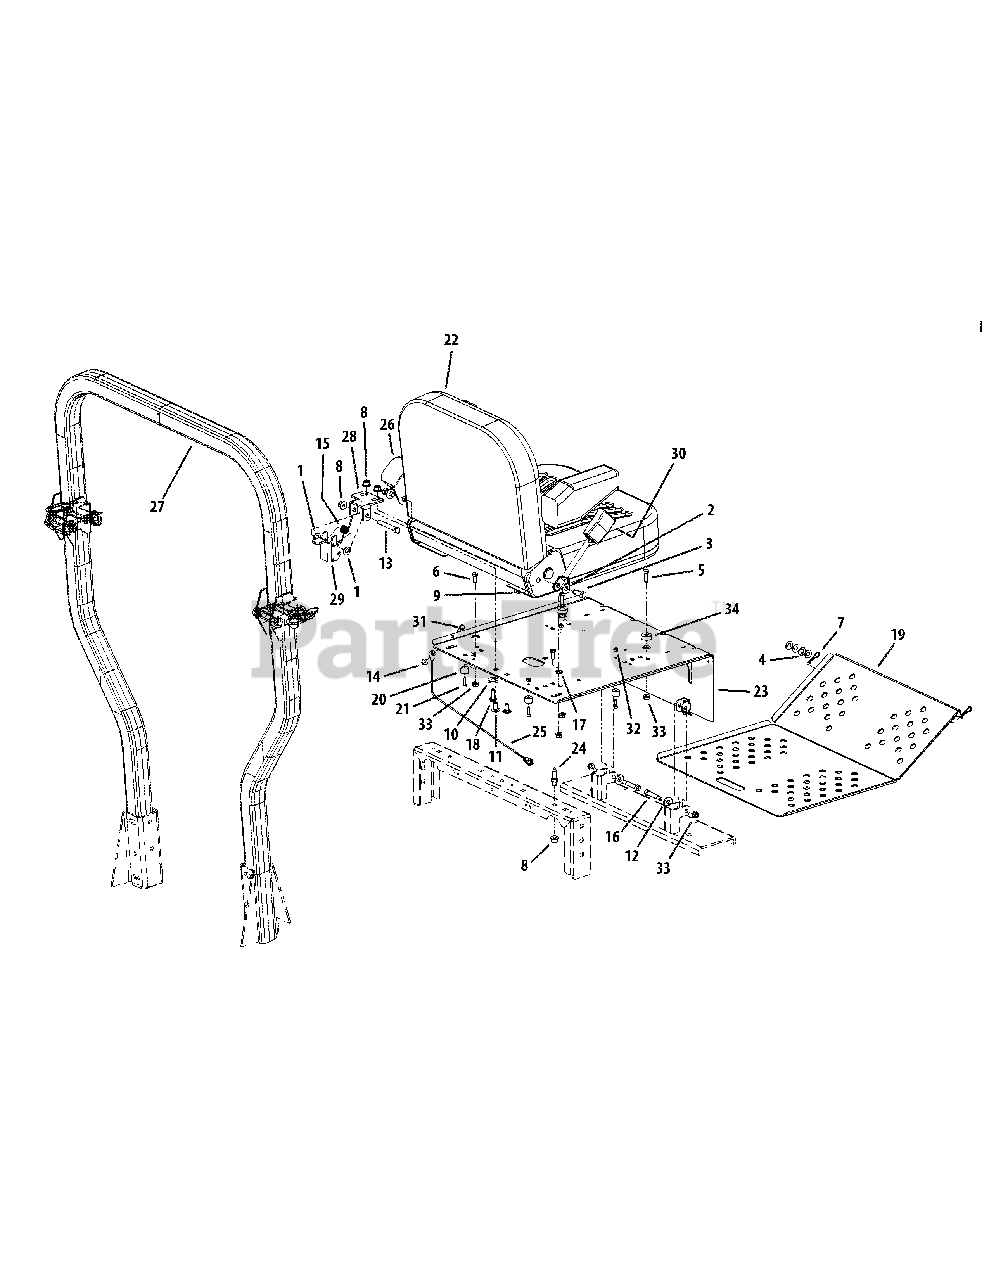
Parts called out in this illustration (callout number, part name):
1	Flat Washer, 3/8 Nylon
2	Flat Washer, 3/8
3	Hex Cap Screw, 7/16-14 x 1.00
4	Washer
5	Hex Head Capscrew, 5/16-18 x 1.00
6	Hex Head Capscrew, 5/16-18 x .75
7	Hair Pin, 3/8-1/2
8	Flange Lock, Hex Nut, 3/8-16
9	Nylock Nut, 7/16-14
10	Washer, .390 ID x 1.0 OD x .180
11	Carriage Bolt, 3/8-16 x .75 Long
12	Flat Washer, .406 ID, 1.0 OD, .105
13	Hex Cap Screw 3/8-16 x 2.75
14	Lock Nut, 1/4-20
15	Deck Lift Spring, Left Hand
16	Shoulder Bolt, .375 x 1.50
17	Push Retainer, 5/16
18	Self Tapping Screw 5/16-18 x 1.00
19	Floor Panel Assembly
20	Rubber Stop with Washer
21	Standard Cap Screw, #10-24 x .75
22	Seat includes:
23	Seat Plate Assembly
24	Adjustable Stud
25	Cable Support
27	Foldable Rops Assembly includes:
28	Seat Latch Bracket
29	Seat Latch
30	Seatbelt Buckle
31	Screw, Hex, Cap, 1/4-20 x .75
32	Nut, #10-24, Nylon Lock
33	Nut, 5/16-18, Flangelock
34	Spacer .406 ID x 1.0 OD
